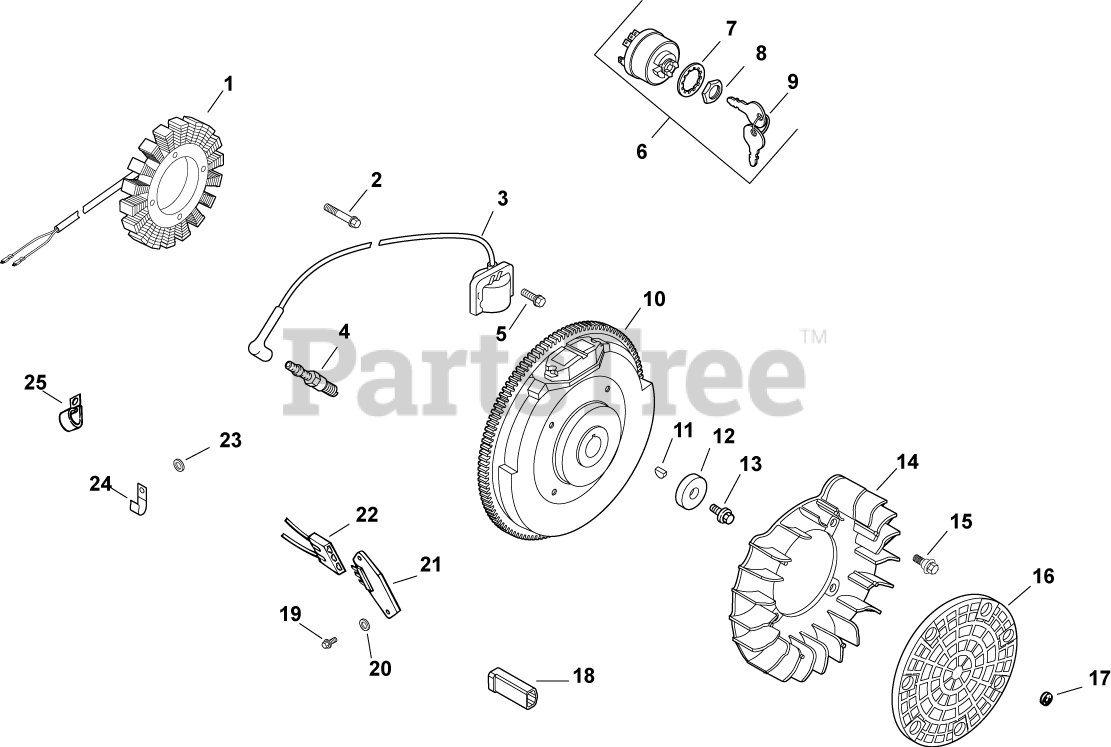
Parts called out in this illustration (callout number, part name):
1	KIT, 15 / 20 AMP STATOR
2	SCREW, M5X0.8X25 - (#25086402S)
3	KIT, MODULE IGNTN (CDI FIXED)
4	PLUG, SPARK (STD)
5	SCREW, FLG THD FRM M5X.8X20-(#25086399S)
6	SWITCH ASSY, KEY (KM)-USE 25 099 32-S
7	WASHER, INTERNAL TOOTH
8	NUT, KEY SWITCH
9	KEY, SET -USE 48 340 01-S
10	FLYWHEEL, PAINTED-USE 24 025 55-S
11	KEY, 3/16" X 5/8"
12	WASHER, FLAT 13/32"
13	SCREW, FLG M10X1.5X45 - (#25086361S)
14	FAN - USE (#24 157 11-S)
15	BOLT, SHOULDER
16	SCREEN, GRASS
18	CONNECTOR (1 CONTACT)
19	SCREW, PHL HD #11-16X7/8"
20	WASHER, FLAT 3/16"
21	REG/RECT-15 AMP (KM)-USE 41 403 10-S
22	CONNECTOR, BODY (KM)-USE 25 155 41-S
23	WASHER, FLAT 1/4" (O.D. 1/2")
24	CLIP, CABLE
25	CLIP, TUBE & WIRING (KM)
